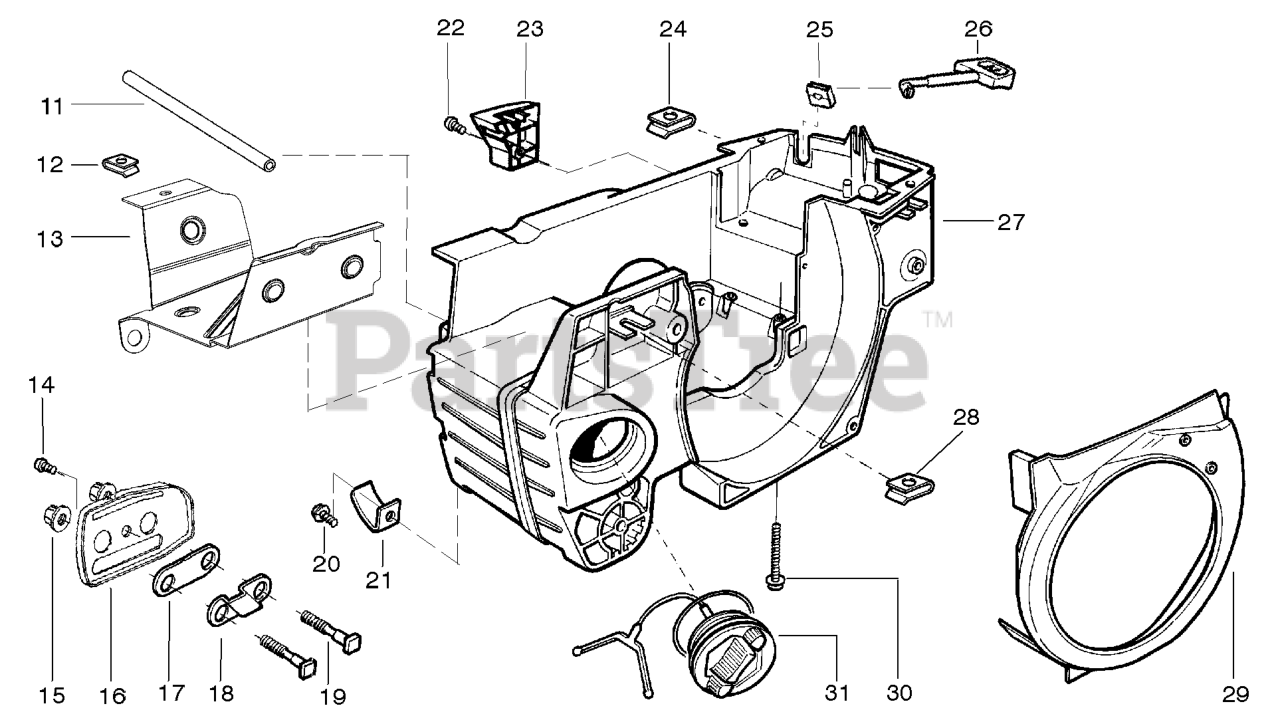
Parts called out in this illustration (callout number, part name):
12	CLIP-U
13	HEATSHIELD, LOWER
14	SCREW
17	OIL TANK GASKET
18	PLATE,BAR MOUNT
19	BAR BOLT 36/41
21	CHAIN CATCHER 36/41
23	LIMITER COVER
25	CHOKE GUIDE 36/41
26	CHOKE 36/41
27	CRANKCASE ASSY
29	AIR CONDUCTOR 36/41
30	SCREW M5-0.8X35M TAP
